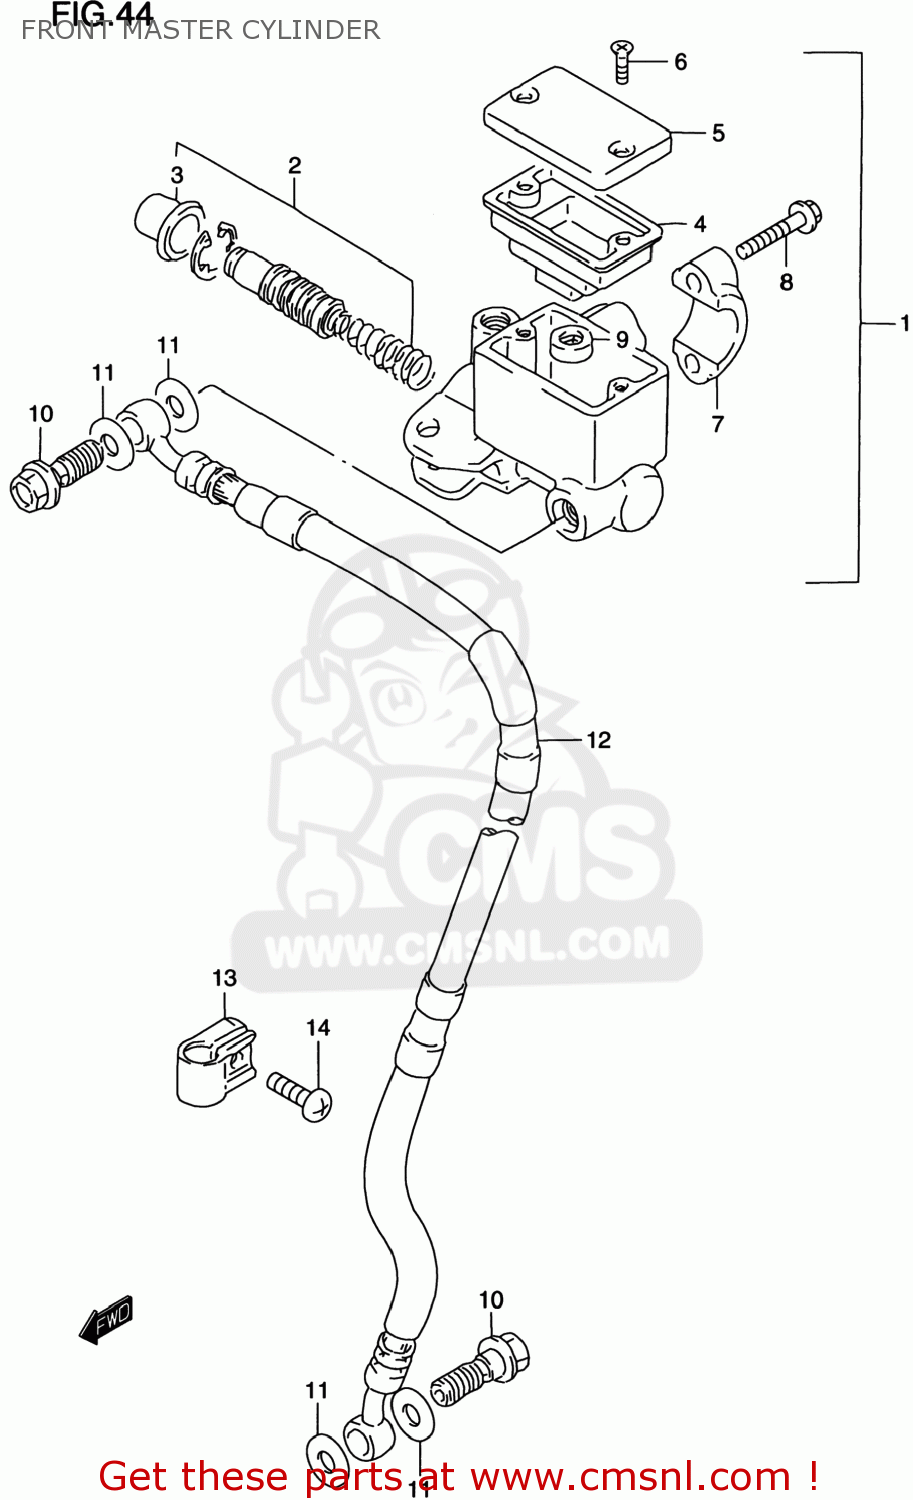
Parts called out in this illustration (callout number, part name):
1	CYLINDER ASSEMBLY,FRONT MASTER
2	PISTON/CUP SET
3	BOOT
4	DIAPHRAGM
5	CAP
6	SCREW
7	HOLDER
8	BOLT
9	SEPARATOR
10	BOLT UNION
11	WASHER(10X15X1.5)
12	HOSE COMP,FRONT BRAKE
13	CLAMP,BRAKE HOSE
14	SCREW
